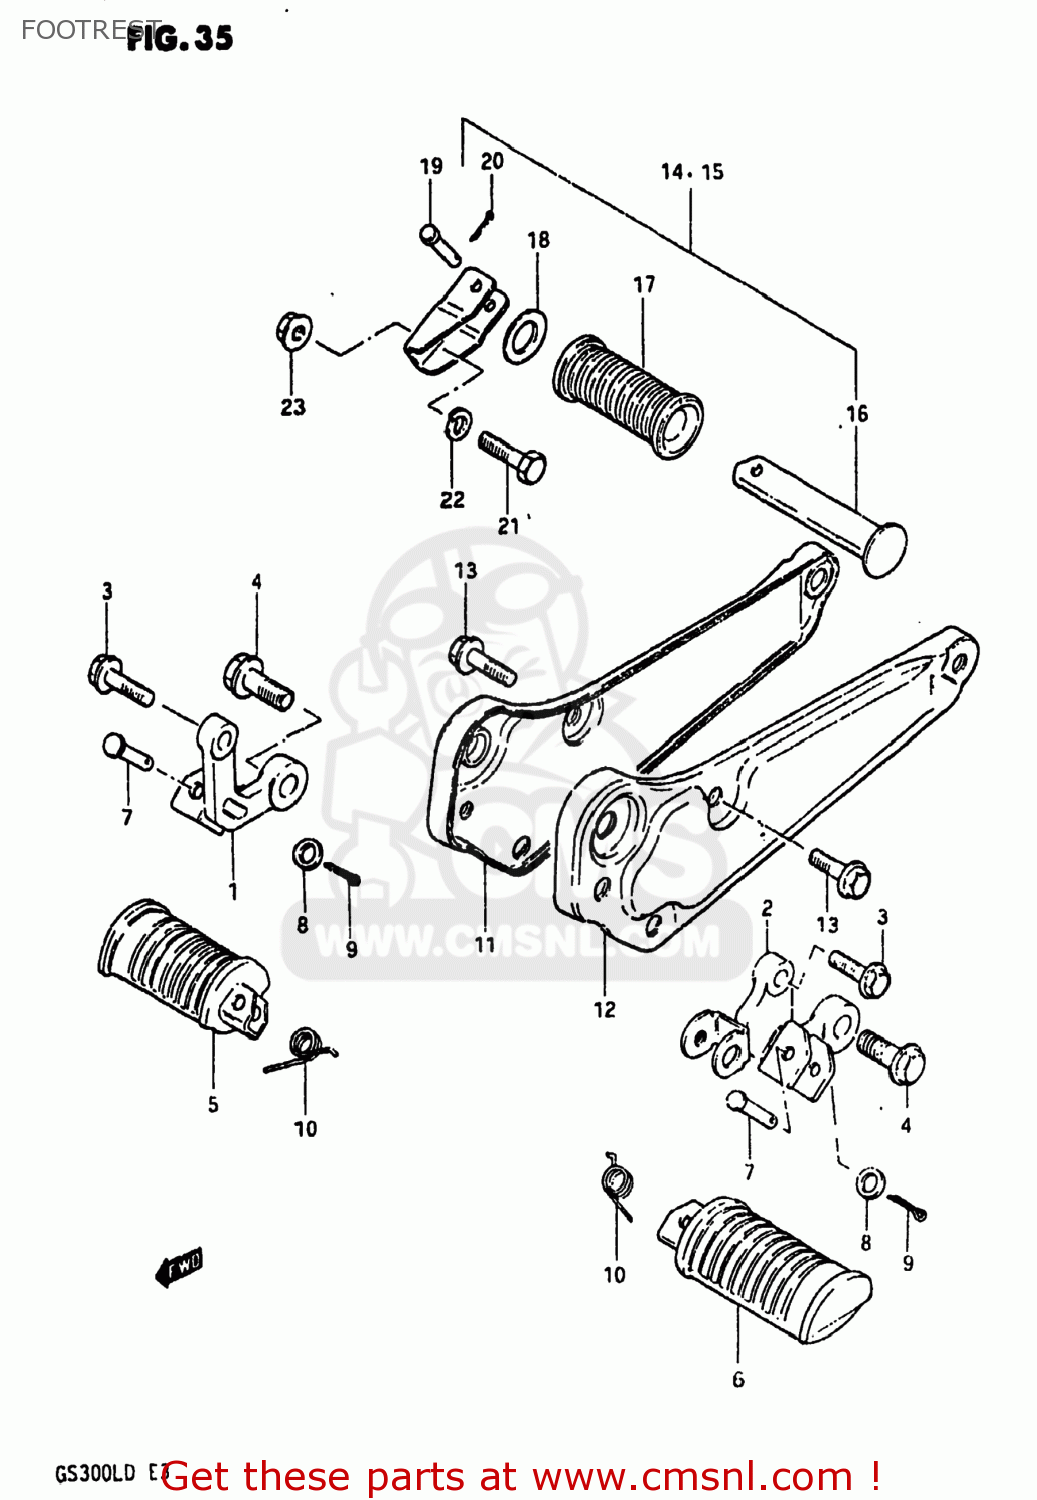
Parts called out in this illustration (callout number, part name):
1	BAR,FRONT FOOTREST
2	BAR,FRONT FOOTREST,LEFT
3	BOLT
4	BOLT
5	RUBBER,FRONT FOOTREST
6	FOOTREST
7	PIN
8	WASHER
9	PIN 20X20
10	SPRING
11	BRACKET,MUFFLER,RIGHT
12	BRACKET,MUFFLER,LEFT
13	BOLT
14	FOOTREST ASSEMBLY,PILLION
15	FOOTREST ASSEMBLY,LEFT
16	BAR,PILLION FOOTREST
17	RUBBER,PILLION FOOTREST
18	WASHER (19.5X32X2)
19	PIN
20	PIN 20X20
21	BOLT,M10X1.25X
22	LOCK WASHER
23	NUT
